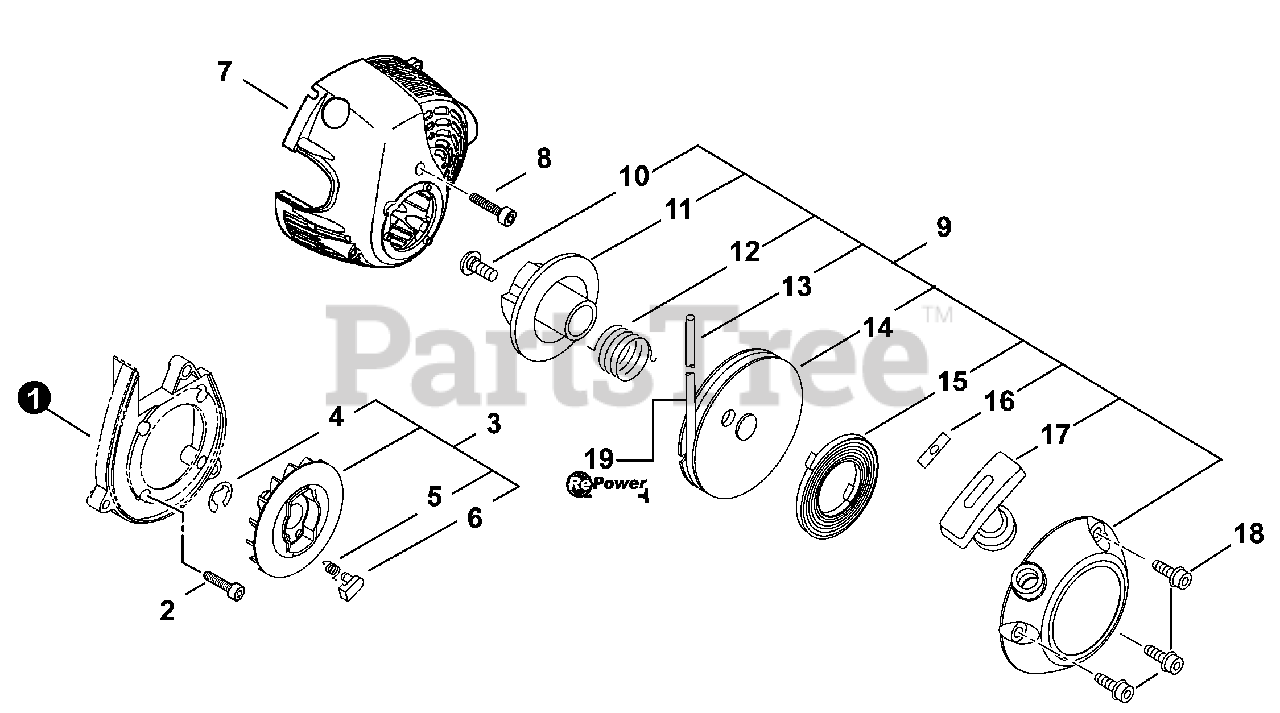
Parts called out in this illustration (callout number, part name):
2	BOLT 4×16
3	PAWL ASSY, STARTER
4	E-RING 4
5	SPRING, RETURN
6	PAWL, STARTER
7	COVER, ENGINE
8	SCREW TAPPING 5×20
9	STARTER ASSY, RECOIL
10	SCREW
11	PLATE, CAM
12	SPRING, TORSION
13	ROPE, STARTER 3×700
14	REEL, ROPE
15	SPRING, RECOIL
16	RETAINER, ROPE
17	GRIP, STARTER
18	SCREW TAPPING 5×16
19	ROPE, STARTER - REPOWER BULK 3
